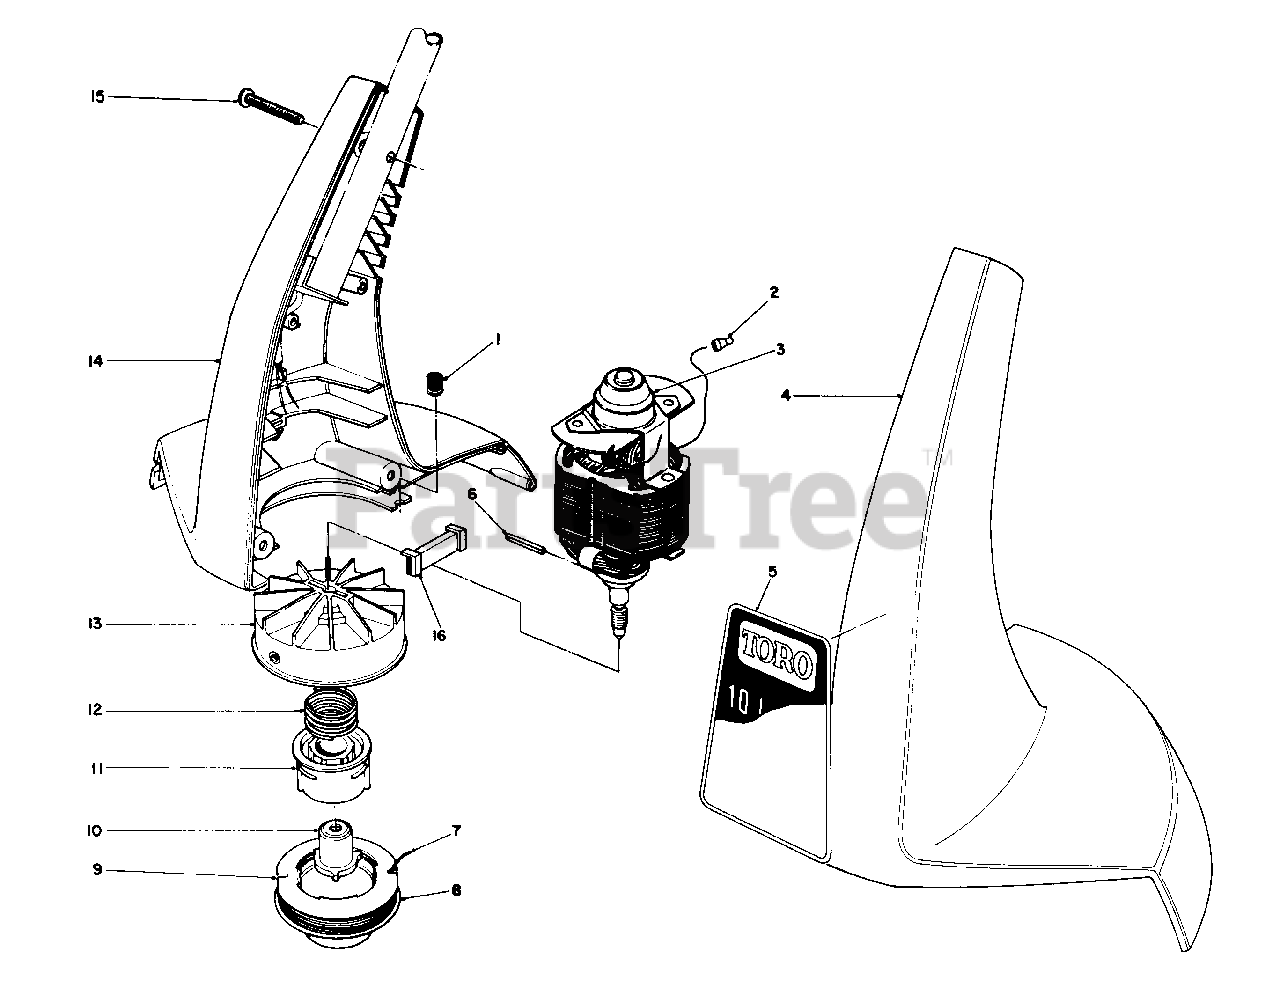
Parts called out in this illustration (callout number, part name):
2	Connector-Electric
4	Housing-Left Hand
5	Decal-Housing
7	Line-Cutting (30' .05 Dia.)
8	Cap-Spool
9	Line-Cutting (30' .05 Dia.Prewound on Spool)
10	Driver-Detent
11	Core-Spool
12	Spring-Compression
13	Fan Hub Assembly
14	Housing-Right Hand
15	Screw-Thread Forming
16	Insert-Housing
